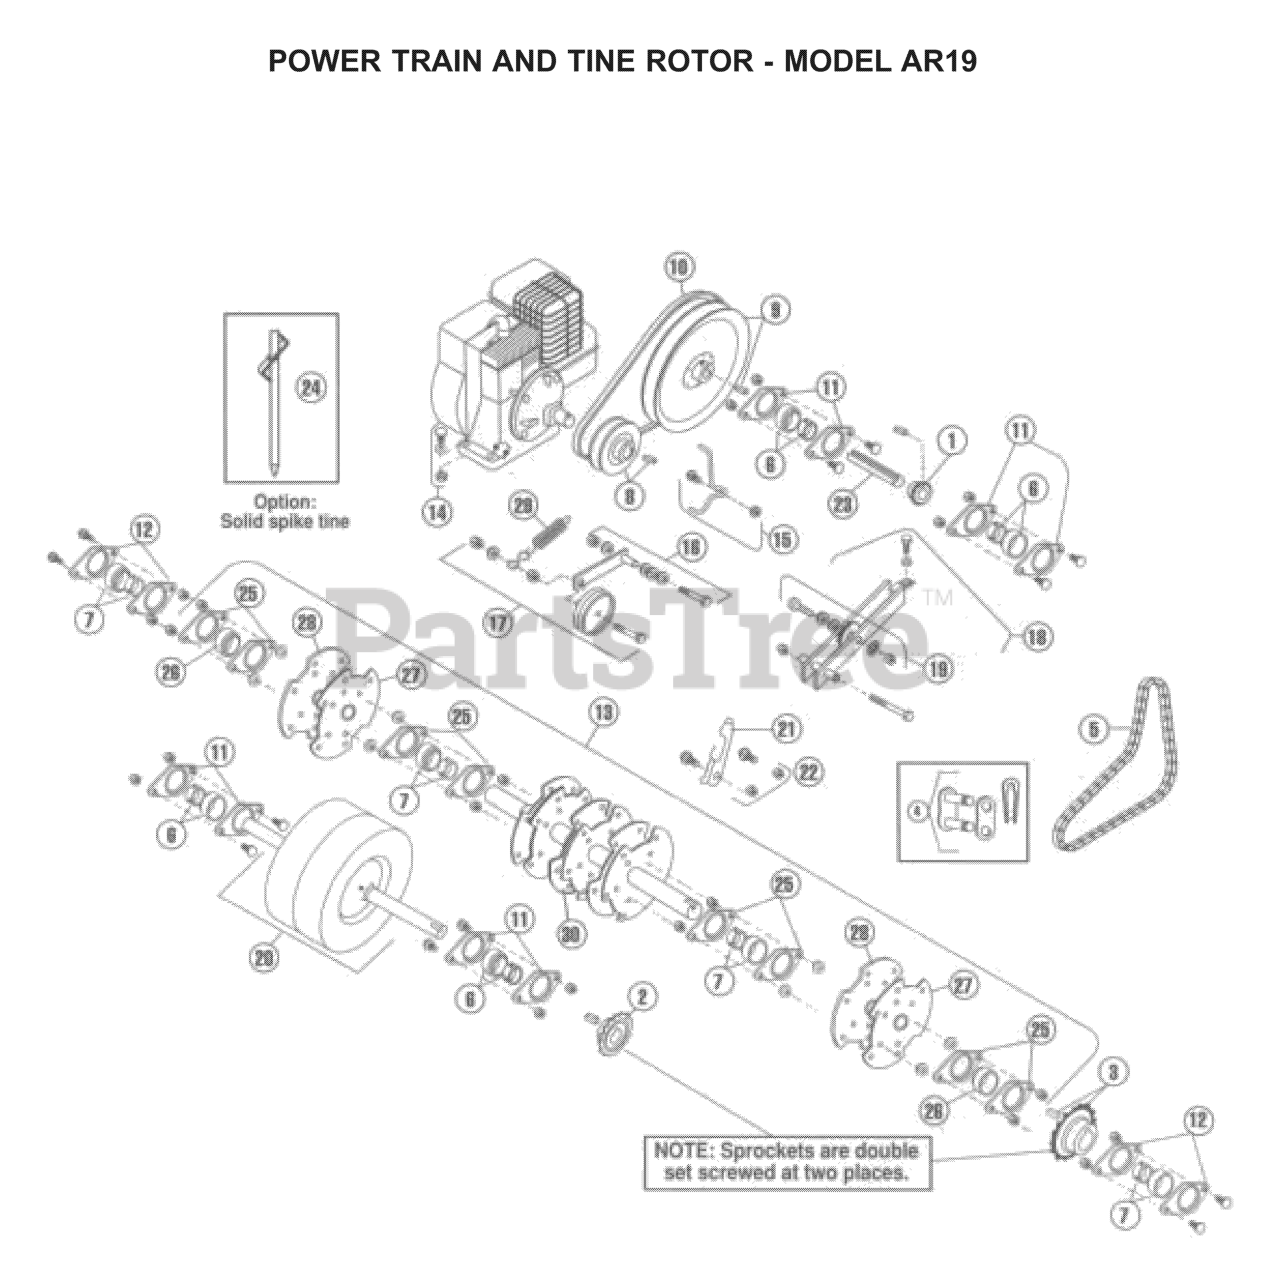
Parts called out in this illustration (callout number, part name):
1	SPROCKET/JACKSHAFT W/SPACER
2	SPROCKET W/KEY, WHEEL
3	SPROCKET
4	CHAIN LINK #40
5	CHAIN #40
6	BEARING
7	BEARING 1"
8	V-PULLEY, A-4"X3/4" BORE W/KEY
9	V-PULLEY
10	ENGINE BELT - V
11	STAMPING KIT
12	STAMPING KIT
13	ROTOR SHAFT
14	FASTENER KIT
15	BELT KEEPER KIT
16	IDLER ARM KIT
17	IDLER PULLEY KIT
18	IDLER ARM KIT W/SPROCKET
19	IDLER SPROCKET KIT
20	FRONT WHEEL
21	TINE SET - 30 EACH
22	TINE/SPIKE FASTENER KIT
23	JACK SHAFT
25	STAMPING KIT
26	BEARING
27	LEFT ROTOR PLATE
28	RIGHT ROTOR PLATE
29	SPRING
30	ROTOR SHAFT
540007103	BOLT KIT
540007112	TINE SET
